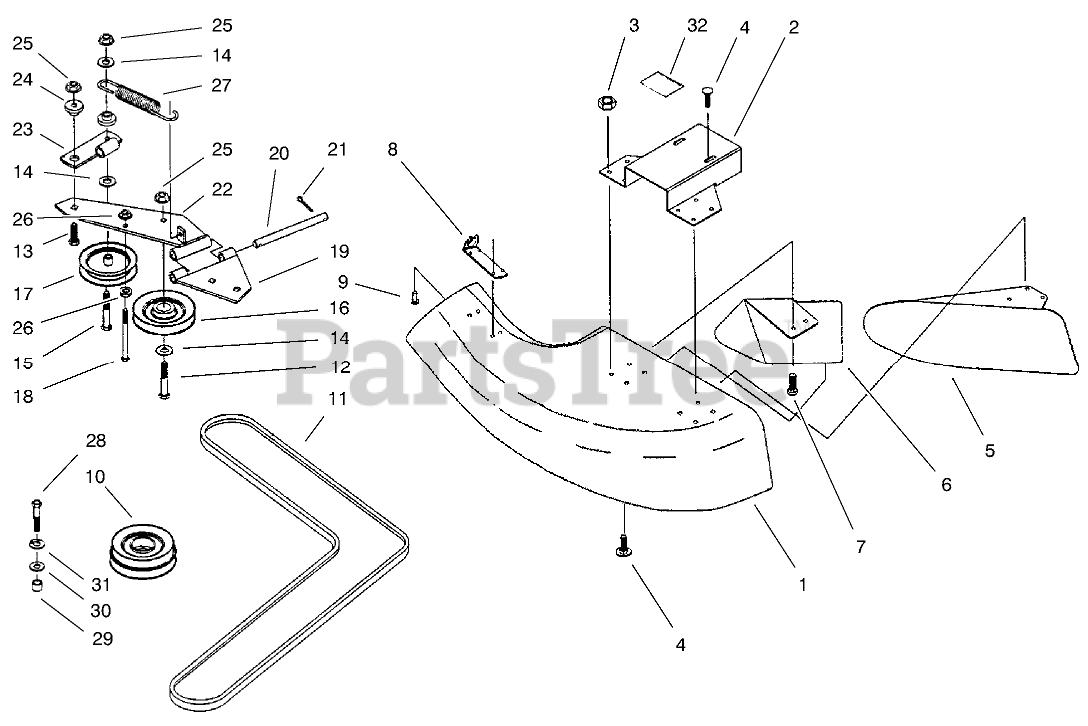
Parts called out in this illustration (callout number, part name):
1	BOOT-SUCTION
2	Fixation-Boot (Incl. Ref. #32)
3	NUT-HF
4	SCREW
5	BAFFLE
6	BAFFLE
7	SCREW-HEAD, TRUSS
8	BRACKET-LATCH
9	RIVET-POP
10	PULLEY-DOUBLE
11	BELT-V
12	SCREW-HH
13	BOLT-CARR
14	WASHER-FLAT
15	SCREW-HH
16	IDLER-V
17	IDLER-FLAT
18	SCREW-HH
19	HINGE
21	PIN-COTTER
22	HOLDER-IDLER
23	ARM-IDLER
24	WASHER-FLANGE
25	NUT-LOCK, NI
26	NUT-HF
27	SPRING
28	SCREW-HH
29	SPACER-GUARD
30	WASHER-PLAIN
31	WASHER-LOCK
32	DECAL-DANGER
